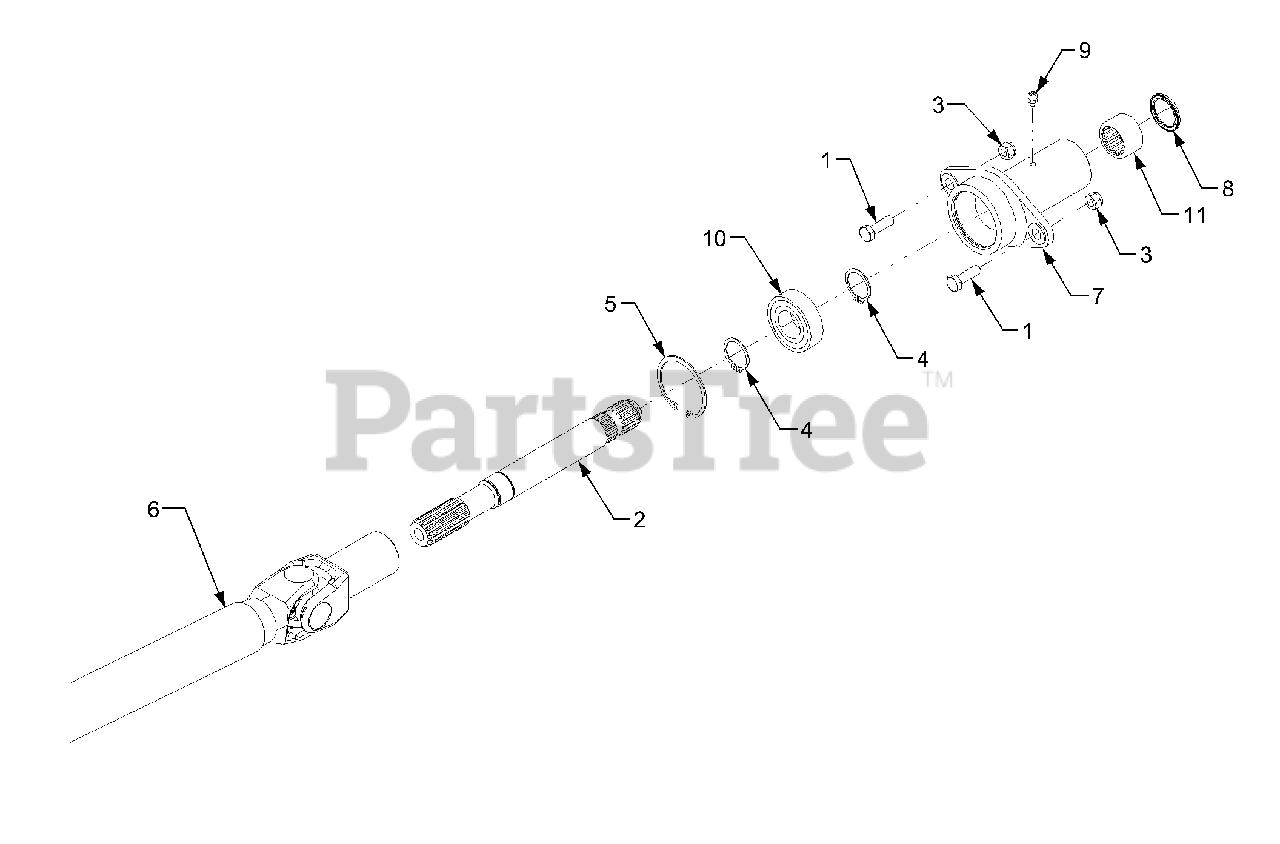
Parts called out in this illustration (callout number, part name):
1	Screw, Hex Cap, 5/16-18 x 1.0 GR5
2	Shaft, Splined, 1.0 Dia.
3	Nut, Hex Insert Lock, 5/16-18 GR5
4	Ring, Snap, 1.0 Dia. Shaft
5	Ring, Internal Retaining, 2.0 Dia
6	Shaft, Drive
7	Carrier, Shaft
8	Seal, Oil, 1.31 x 1.0
9	Fitting, Lube
10	Bearing, Ball
11	Bearing, Needle, 1.0 x 1.3125 x .75
